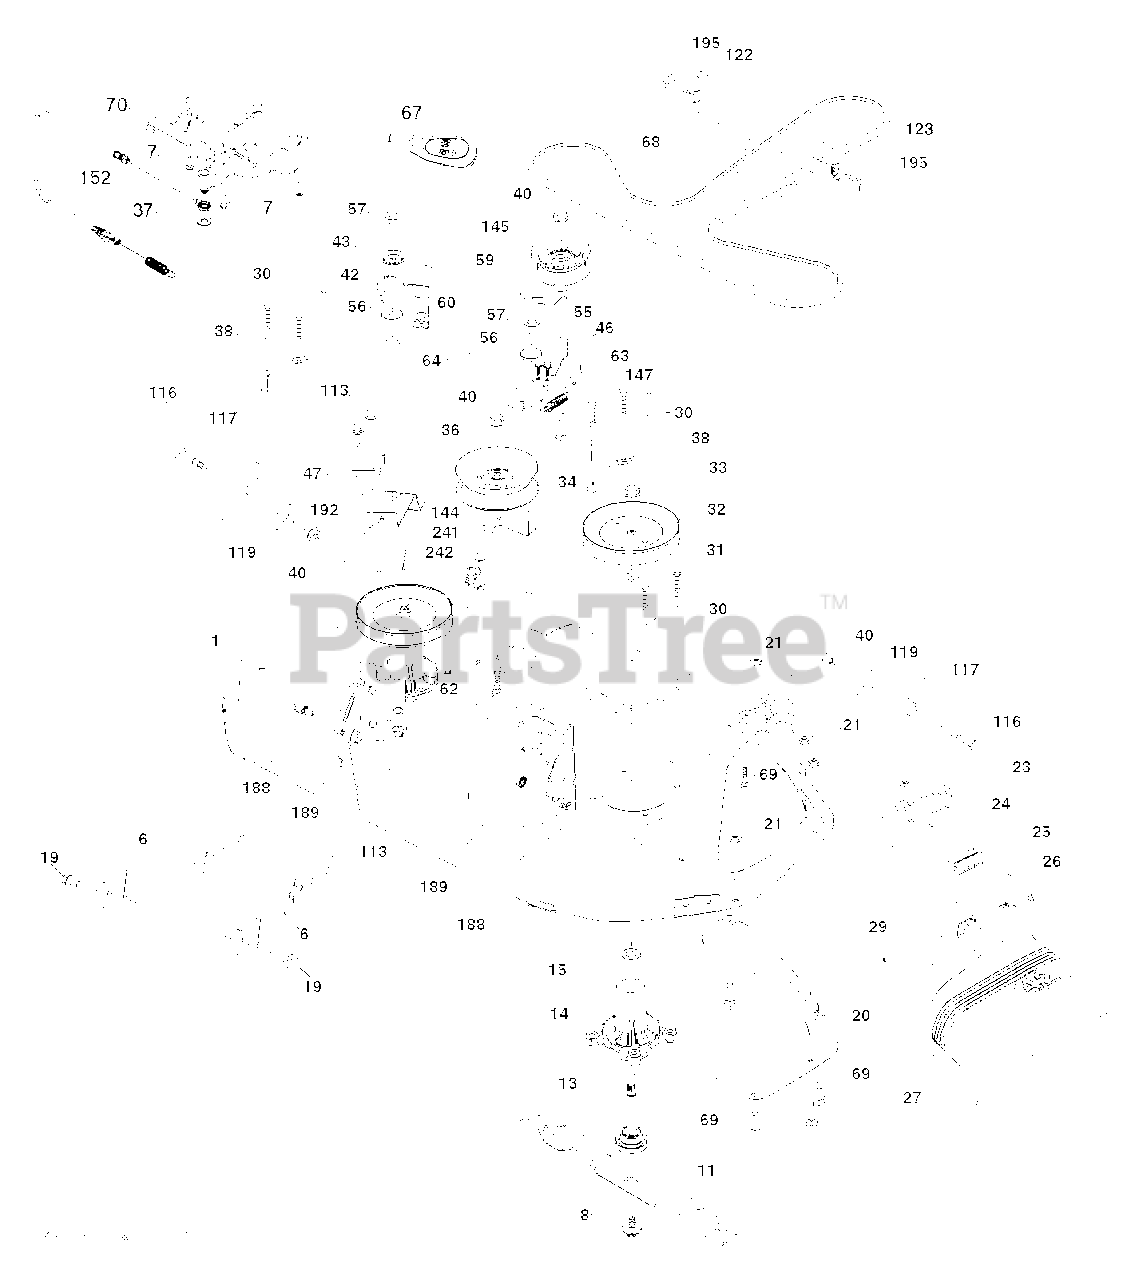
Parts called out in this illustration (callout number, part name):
1	DECK.WELDMNT.42"GREYMS498
6	ARM.SUSPENSION.MOWER.R
7	SCREW.#10 X 0.750.BOS
8	BOLT.WASHER.ASM.7/16-2
11	42" HI-LIFT BLADE
13	SHAFT.ASM.MDRL.N/GREASE.38
14	HOUSING.MANDREL.4PT.
19	BOLT.SHOULDER
20	BAFFLE.VORTEX
21	LOCKNUT
23	BRKT.DEFLECTOR.38"2005+
24	CAP-SLEEVE LT
25	SPRING.TORSION.DEFLECT
26	NUT PUSH M
27	SHIELD.DEFLECTOR.MOWER.42"BLAC
29	ROD.HINGE
30	SCREW, WASHER HEAD
31	WASHER.SPACER.MANDREL
32	PULLEY.MANDREL.5.438.PD
33	NUT.FLANGE.LOCK.TOP
34	BOLT.3/8-16X1.50
36	PULLEY.IDLER.2006
37	WASHER
38	KEEPER.BELT.MANDREL.PULLEY
40	NUT LOCK FLG 3/8-16 UNC
42	SPRING.TORSION.BRAKE
43	SRPING.TORSION.RETAINE
46	SCREW.1/4-20X5/8
47	BRKT.CLUTCH.CABLE
55	IDLER.ARM.42"
56	SPACER.RETAINER
57	SCREW 3/8-16X1
59	GUARD, BELT
60	ARM BRAKE MOWER
63	ARM BRAKE MOWER
64	LINKAGE.BRAKE.ASM.ZINC
67	HANDLE.CLUTCH.CABLE.LT
68	BELT.DECK.DRIVE.42"
69	BOLT
70	CLUTCH.ASM.MANUAL.YT.PREDATORQ
113	BOLT.5/16HEX.WHS.HD
116	BOLT M
117	WHEEL.GAGE.HALF.SPOKED
119	WASHER
122	KEEPER BELT ENGINE LH
123	KEEPER BELT RH
144	KEEPER.BELT.MOWER
145	PULLEY.IDLER.48"PRIMARY
147	RETURN SPRING
152	CABLE.CLUTCH.CABLE.W/SPRING
188	STUD.FASTNER.W/ANTI-ROTATE
189	NUT LOCK HEX FLANGE 5/16-18
192	BRKT.BRAKE.STAND.LH.
195	SCREW, 3/8-16X3/4
241	SCREW.TT.#10-32X.5.3/8.FLANGE
242	PORT.WASHOUT
